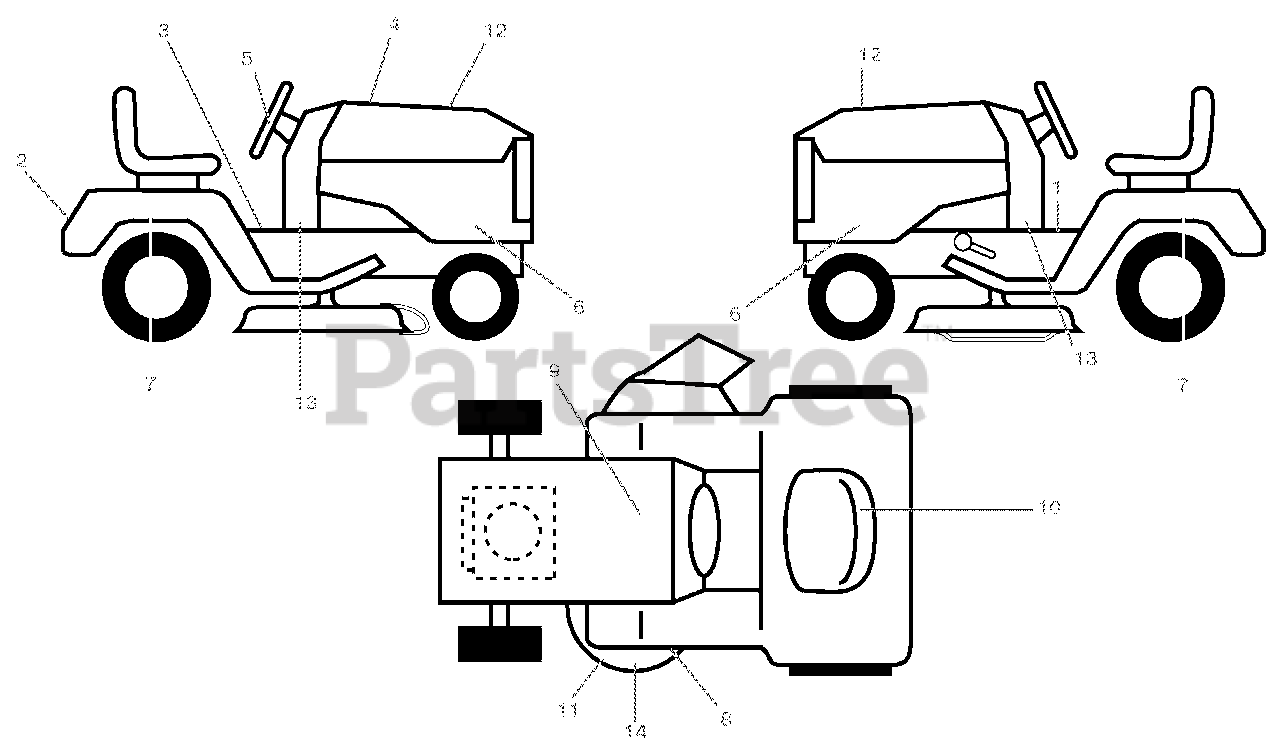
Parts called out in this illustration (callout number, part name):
1	DECAL, WARNING START INST.
2	DECAL.FENDER.REAR.ARIENS
3	DECAL.FENDER
4	DECAL, REPLACEMENT
5	DECAL.WHEEL.STEER.ARIENS
6	DECAL.SDPNL.PWRDBY KOHL.ARIENS
7	DECAL, FENDER
8	DECAL.MOWER.SCH.48/54.PREM.
9	DECAL.BAT.DAN/POI P/L SYM.WPN
10	Decal Fender Service
11	DECAL.MOWER.CAUTION.TENSION.AR
12	DECAL.HOOD.RH.PRECISION.ARIENS
13	DECAL.DASH.LOWER
14	DECAL.MOWER.WARN.KEEP HAND AWY
